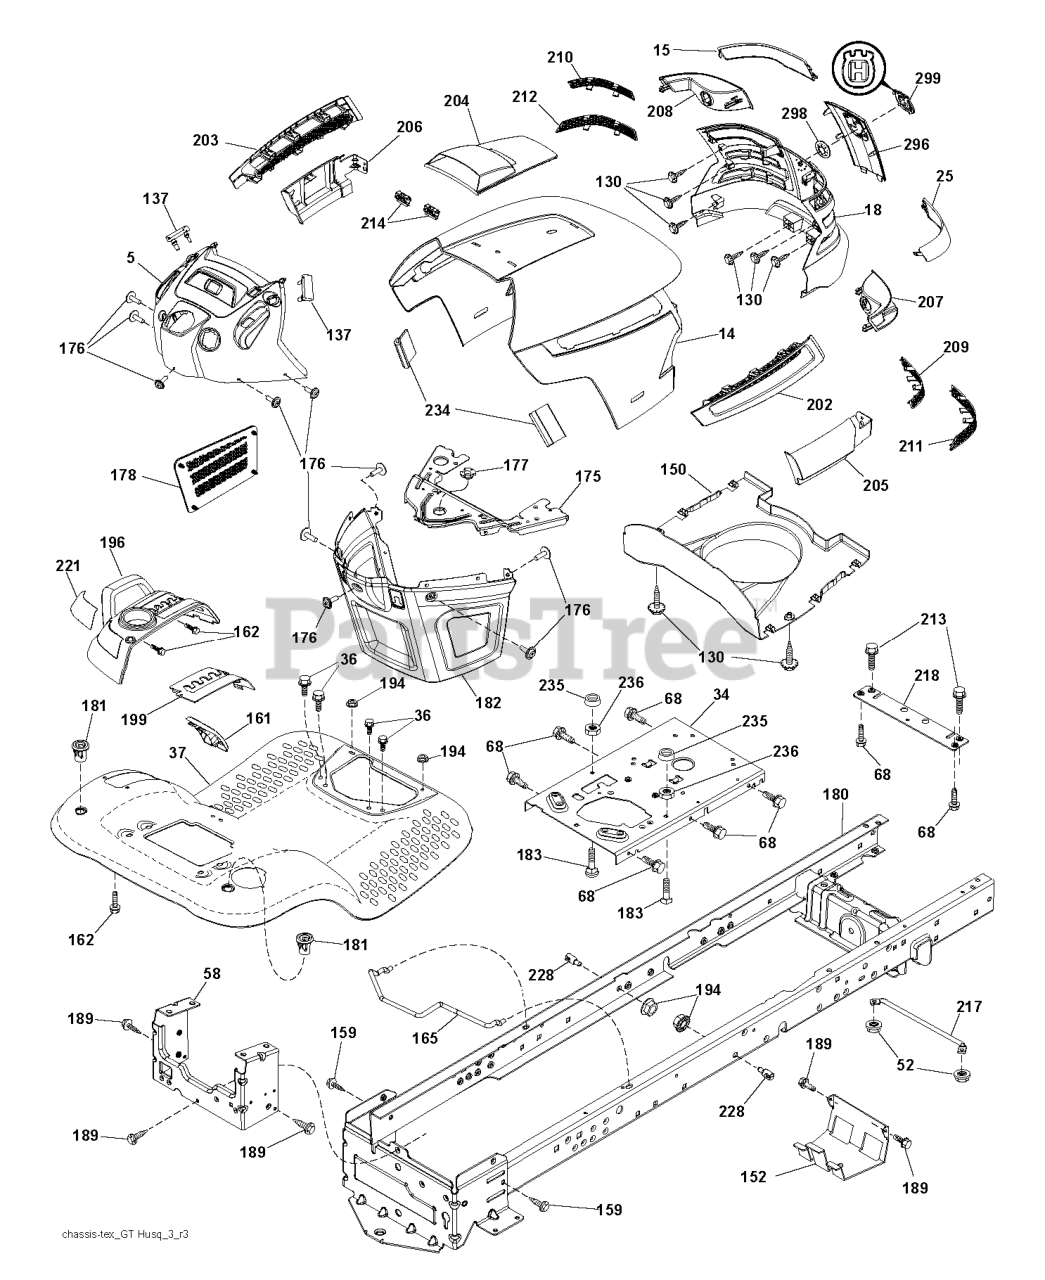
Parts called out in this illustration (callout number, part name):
3	RP LOGO
5	DASH.ASM.HUSQ.GT.E.RECT.W/CK
14	HOOD
15	LENS.LH.TEX.GT.HUSQ.CL
18	GRILL.ASM.HUSQ.TG/CRD.W/TRIM
25	LENS.RH.TEX.GT.HUSQ.CL
34	PLATE.ENGINE.WELDED.CHASSIS
36	SCREW 5/16"
37	FENDER.PNT.TX.GT.CH/FW.ORANGE
52	LOCKNUT
58	DRAWBAR.UPPER.2PC,LRG.FENDER
68	Screw 5/16-18 x 1/2 Hex, Self Tapping 5/16-18 x 1/2
130	SCREW.#10 X 0.750.BOS
137	BUMPER DASH
150	AIR.DUCT.HOOD.TEX.GT.HUSQ
152	SHIELD.BROWNING.W/TEX
159	SCREW, 3/8-16X3/4
161	CONSOLE.FUEL.WINDOW.HU
162	SCREW.HI-LO.CONSOLE
165	SUPPORT.TANK.REAR.W/TEX
175	PLATE.CROSSMEMBER.HUSQ
176	SCREW.#10-24X5/8.RN.QU
177	BUSHING, STEERING
178	CARGO.ASM.NET.TXGT.W/C
180	CHASS.WLDMNT.TLT.12GA/2PC.20"
181	BUSHING.MNT.FEND.CRGO.
182	DASH.LOWER.COMMON.12V.ADAPTOR
183	BOLT.5/16-18X1-1/4 FULL.THREAD
189	SCREW
194	NUT LOCK HEX FLANGE 5/16-18
195	PLUG.HOLE.DASH.LOWER.12V.BLK
196	RP CONSOLE.ASM.DECKLFT.W/
199	PLATE.DECK.LIFT.HUSQVARNA.GT
202	VENT.SIDE.HOOD.HUSQ.RH.GREY
203	VENT.SIDE.HOOD.HUSQ.LH.GRAY
204	HOOD VENT
205	SKIRT.HOOD.SIDE.HUSQ.RH.GREY
206	SKIRT.HOOD.SIDE.HUSQ.LH.GREY
207	BEZEL.RH.TEX.GT.HUSQ
208	BEZEL.LH.TEX.GT.HUSQ
209	INSERT.HEX.GRILL.HUSQ.GREY
210	INSERT.HEX.GRILL.HUSQ.
211	INSERT.HEX.GRILL.HUSQ.
212	INSERT.HEX.GRILL.HUSQ.
213	BOLT
214	CLIP.RETAINER.TINNER.
217	ROD.PIVOT.HOOD
218	X-PIECE.HOOD.STOP.NON/
221	REFLECTOR.LH.TEX GT HU
228	STUD.FASTNER.W/ANTI-ROTATE
234	BUMPER.HOOD.TEX.HUSQVARNA
235	SPACER FENDER
236	NUT.CENTERLOCK.5/16-
238	TRIM.HUSQ.TG/CRD.SERVICE
239	NUT PUSH M
